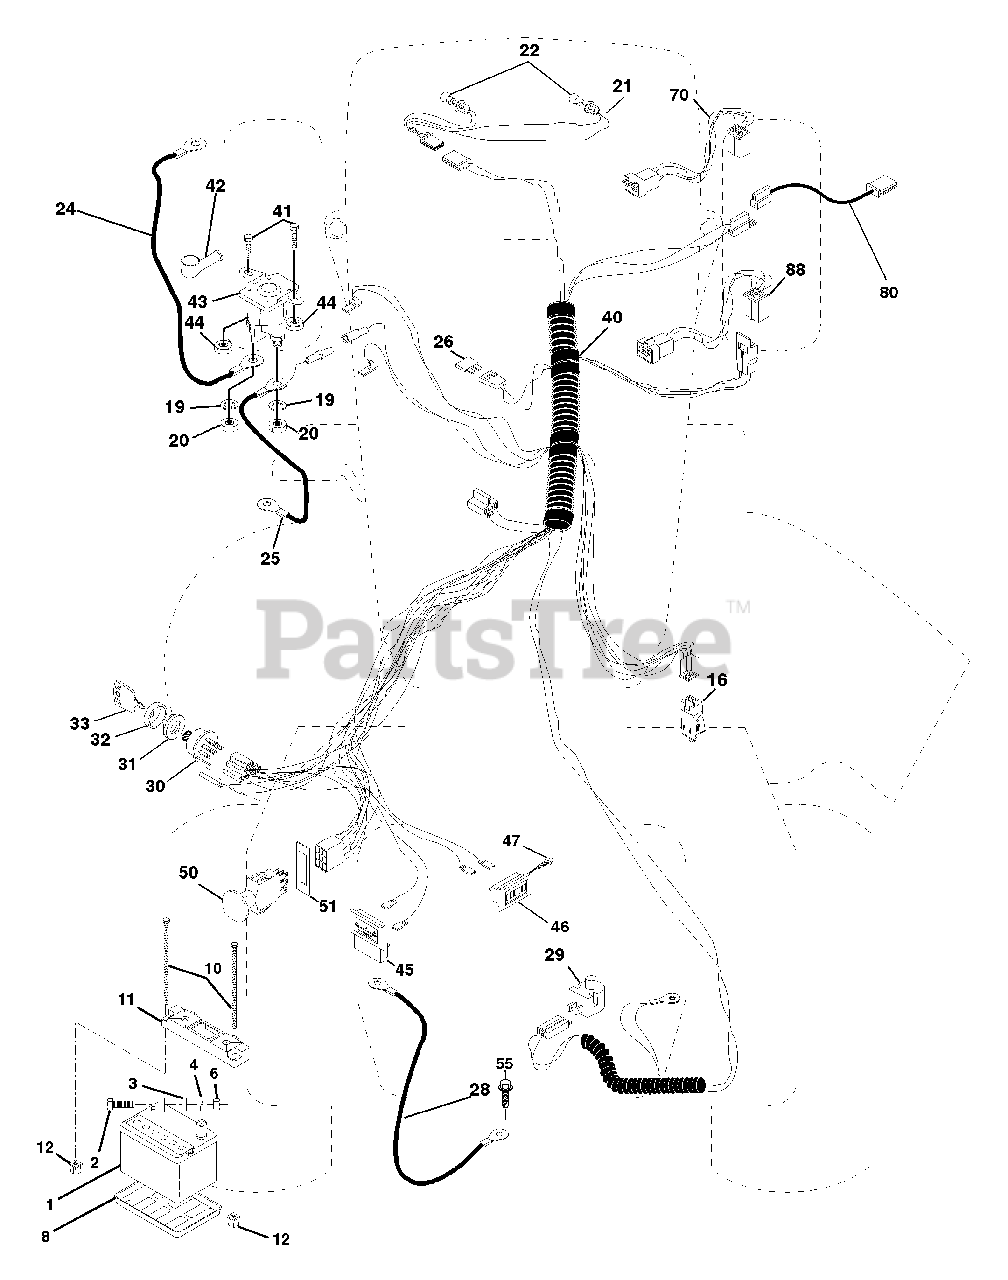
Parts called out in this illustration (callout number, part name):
1	Battery 12 Volt 25 AMP
2	Bolt Hex Hd 1/4-20 unc X 3/4
3	Washer 9/32 X 5/8 X 16 Ga.
4	Washer Lock Hvy Helical 1/4
6	Nut Fin Hex 1/4-20 Unc
8	Tray Battery 7.80 x 5.25 Blk
10	Bolt Btr Frt 1/2-20 x 7.5 Zinc
11	Holddown Battery Front Mount
12	Nut Push Nylon 1/4" Battery Frt
16	Switch Interlock Push-In
19	Washer Lock 1/4
20	Nut Jam Hex 1/4-20 Unc
21	Harness Asm Light W/4152j
22	Bulb Light #1156
24	Cable Battery 6 Ga 11" red
25	Cable Battery 6 Ga 44" red w/16 wire
26	Fuse 30 AMP Auto Green
28	Cable Ground 6 Ga 21" black
29	Switch Plunger Nc Gray
30	Switch Ign 4 pos w/lights
31	Nut Ignition
32	Cover Sw Ignition
33	Key Ign Modelled Generic
40	Harness Ign.
41	Bolt Blk Fin Hex 1/4 - 20 x 1/2
42	Cover Terminal Red
43	Solenoid
44	Nut Keps Hex 1/4-20 Unc
45	Ammeter Rectangular 6 Amp
46	Meter Hour
47	Screw 10-24 x 1/2 Black
50	Switch PTO 3PDT Black Delta 96
51	Ring Retainer PTO
55	Screw Thdrol 5/16-18 x 1/2 Tyt
70	Harness, Eng Kohl Cmd-L Dual
80	Harness Clutch Evx
81	Relay Asm.
88	Harness, Eng. Kohl CV15 Stator
